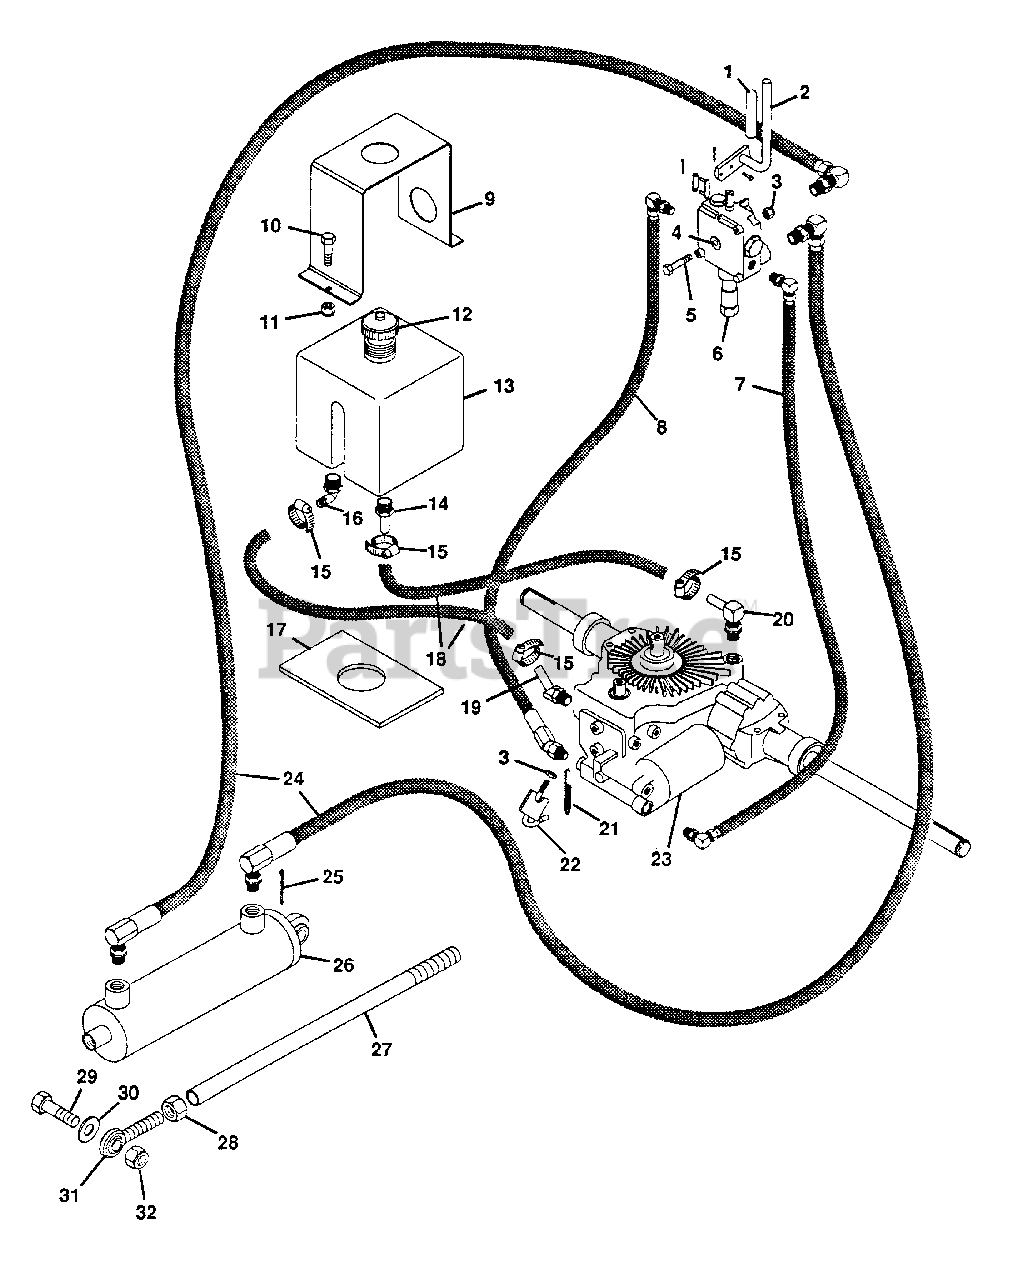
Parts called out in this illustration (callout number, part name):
1	GRIP, PTO LEVER
2	WELDMENT, HANDLE
3	NUT, LOCK 1/4-20
4	WASHER, FLAT .281X.625X.065
5	BOLT, HEX 1/4-20X1.75
6	VALVE, HYDRAULIC
7	ASSEMBLY, HOSE RETURN
8	ASSEMBLY, HOSE PRESSURE
9	BRACKET, TANK
10	BOLT, HEX 5/16-18X.75
11	NUT, LOCK 5/16-18
12	CAP, TANK
13	TANK, HYDRAULIC
14	ADAPTOR, 1/2 NPTX1/2 HOSE
15	CLAMP, .88 DIA. HOSE
16	FITTING, MALE ELBOW
17	PAD, TANK
18	HOSE, 1/2
19	ADAPTOR, HOSE 45 DEGREE
20	ADAPTOR, HOSE
21	SPRING, PTO RETURN
22	WELDMENT, LEVER
23	FILTER, OIL
24	ASSEMBLY, HOSE PRESSURE
25	PIN, COTTER .125X1.25
26	CYLINDER
27	ROD, LIFT
28	NUT, JAM 1/2-20
29	BOLT, HEX 1/2-13X1.75
30	WASHER, FLAT .531X1.062X.095
31	ASSEMBLY, ROD END(R.H.)
32	NUT, LOCK 1/2-13
